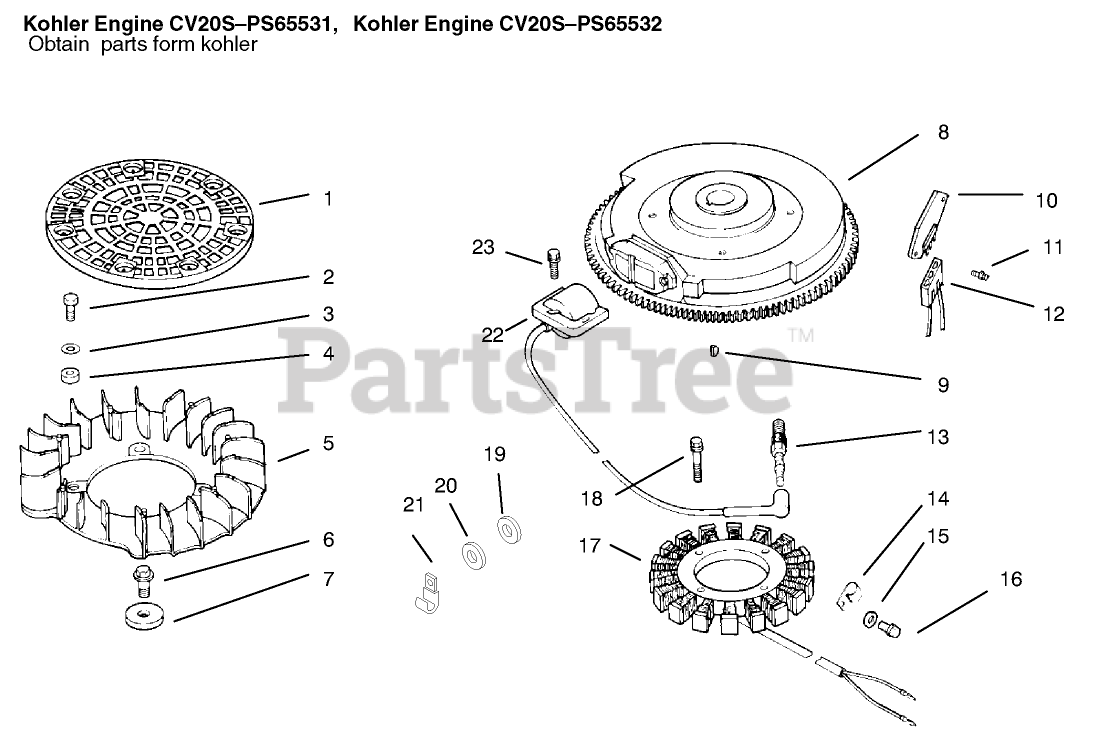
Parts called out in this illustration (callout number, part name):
1	Screen-Grass (Only On: 72103, 72083)
3	Washer
4	Spacer-Fan (Only On: 72103)
5	Fan (Only On: 72103, 72083)
7	Spacer-Fan
8	Flywheel ASM (Only On: 72103, 72083)
10	Rectifier-Regulator
12	Connector
13	Spark Plug
16	Screw
17	Stator-15 amp
19	Washer
20	Washer
22	Module-Ignition
